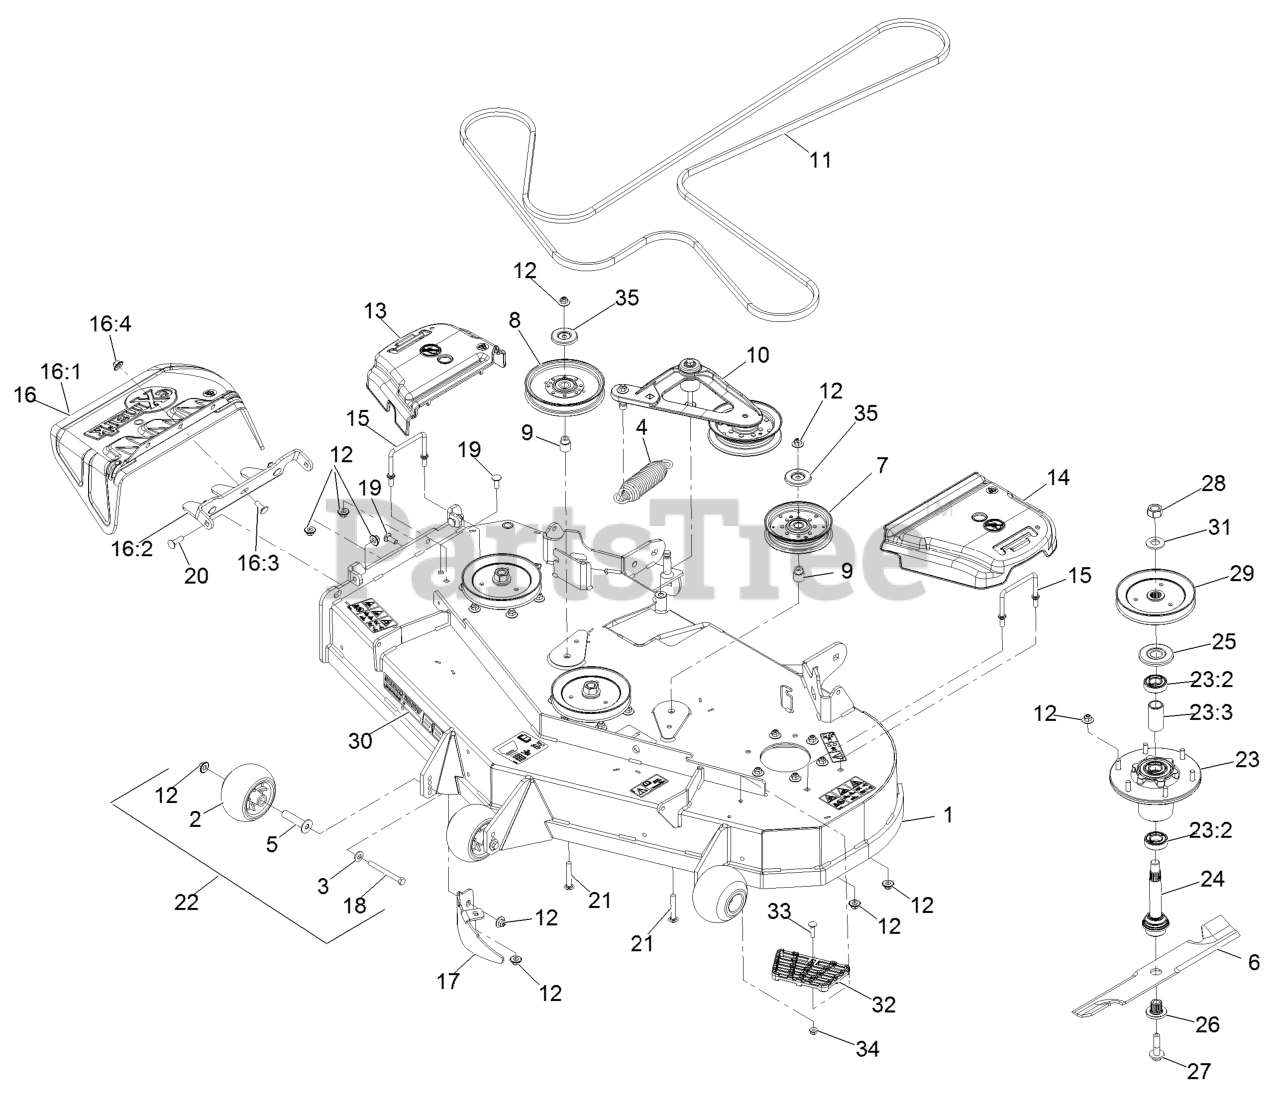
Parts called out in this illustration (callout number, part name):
1	ASM,DECK W/ DECALS 52
2	ROLLER-SCALP, ANTI
3	WASHER-BELLEVILLE
4	SPRING-EXTENSION
5	AXLE, ROLLER
7	PULLEY-IDLER, FLAT
8	IDLER-PULLEY
9	BUSHING-IDLER
10	DECK IDLER ASM
11	BELT,V-B X 186.00"
12	Nut-Nyloc 3/8-16 Flg
13	COVER-BELT, RH
14	COVER-BELT, LH
15	WIREFORM-COVER
16	ASM,DISCHARGE CHUTE
16:1	CHUTE,DISCHARGE
16:2	BRACKET,DISCHARGE CHUTE
16:3	SCREW-CARR
16:4	Nut-Nyloc 3/8-16 Flg
17	BAFFLE-DOGLEG, LZ-VT52
18	SCREW-HH 3/8-16 X 3 3/4 GR 8
19	SCREW-CARR
20	Bolt-Carriage 3/8-16 X 1 1/4
21	SCREW-CARR
22	KIT, ANTI-SCALP ROLLER
23	ASM-CUTTER HSG WITH BEARINGS
23:2	BEARING-BALL
23:3	SPACER-BEARING
24	ASM-SPINDLE AND SEAL
25	GUARD,BEARING TOP .989
26	BUSHING,SPLINED
27	SCREW,SEMS 1/2-20 X 2.19
28	NUT-HEX
29	SHEAVE,BLADE DRIVE 6.50
30	DECAL, 524
32	STEP-DECK
33	Bolt-Carriage 5/16-18 X 1 1/4
34	NUT-HF, NI
35	SHIELD-DUST
